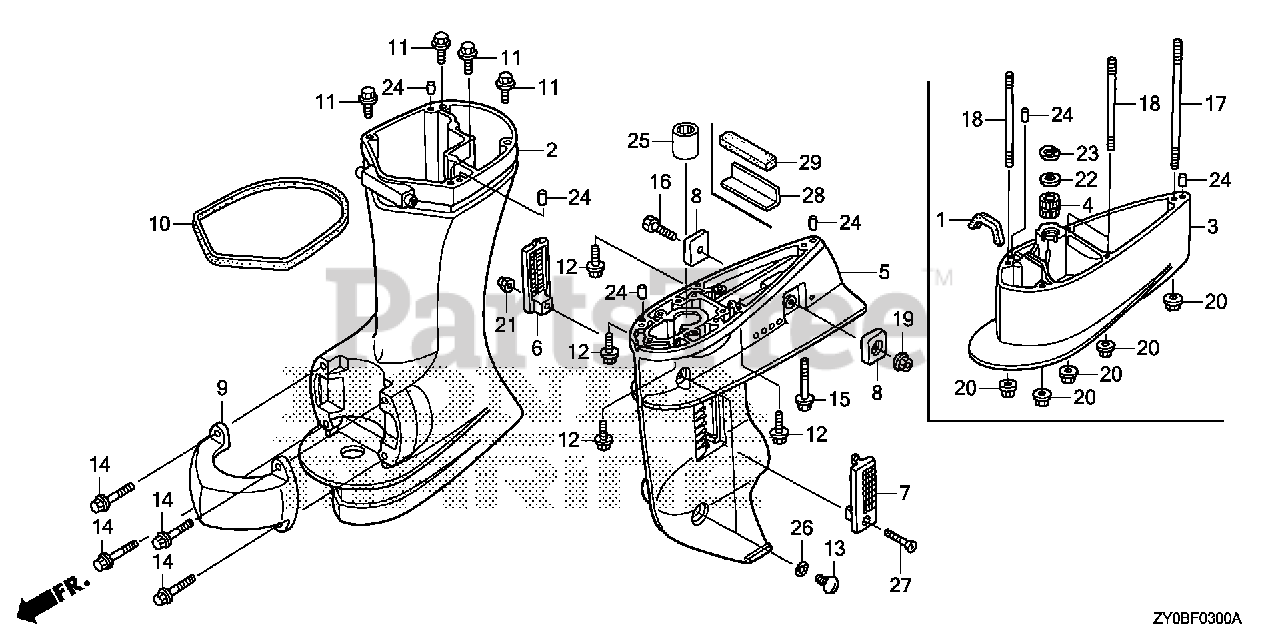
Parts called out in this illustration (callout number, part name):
2	CASE, EXTENSION *NH282MU* (S) (OYSTER SILVER METALLIC-U)
5	CASE, GEAR *NH282MU* (OYSTER SILVER METALLIC-U)
6	SCREEN, R. WATER
7	SCREEN, L. WATER
8	METAL, ANODE
9	HOUSING, MOUNTING (LOWER) *NH282MU* (OYSTER SILVER METALLIC-U)
10	RUBBER, COVER (LOWER)
11	BOLT, FLANGE (8X35) Use from Frame SN 4800713.
12	BOLT, FLANGE (6X23) Use from Frame SN 4800343.
13	BOLT, OIL CHECK
14	BOLT, FLANGE (6X20) (ENGINE NO.)
15	BOLT, FLANGE (6X75)
16	BOLT, HEX. (6X25) Use up to Frame SN 4800342.
19	NUT, SELF-LOCK (6MM)
21	NUT, SELF-LOCK (5MM)
24	PIN, DOWEL (6X10)
25	BEARING, NEEDLE (15X22X20)
26	O-RING (6.9X1.45)
27	SCREW, OVAL (5X28)
28	PLATE, RUBBER SETTING
29	GROMMET, GEAR CASE
